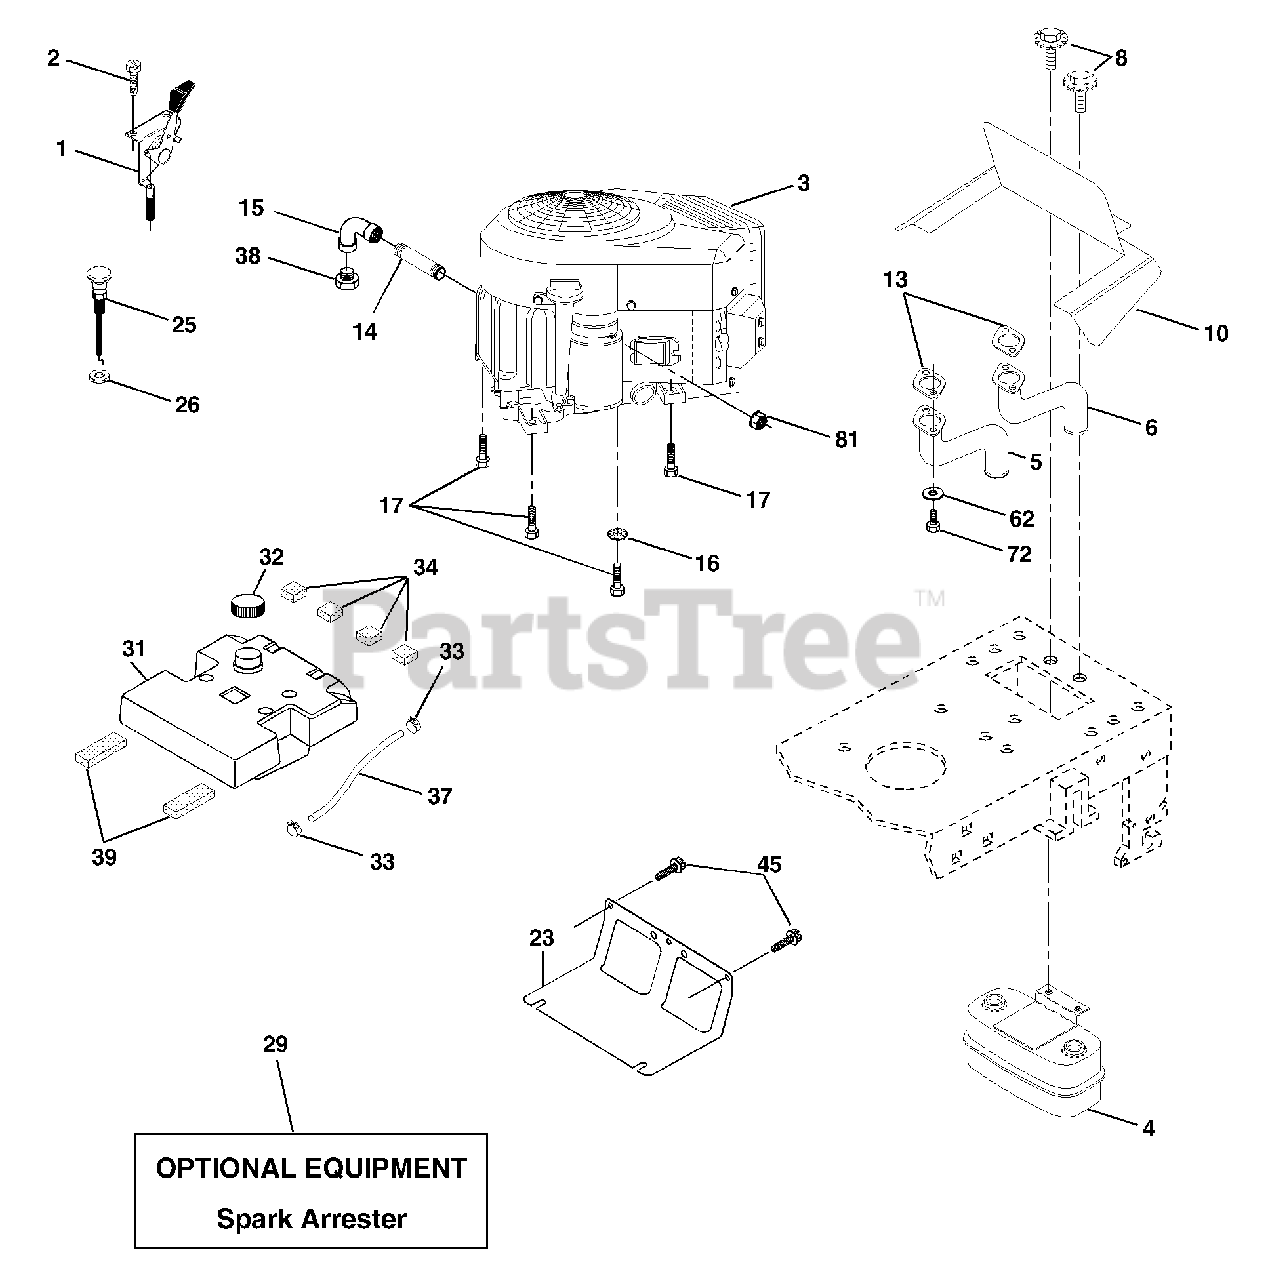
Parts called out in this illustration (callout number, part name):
1	Control Throttle
2	Screw Hwhd Hi-Lo #13-16 x 3/4
4	Muffler Asm Twin Lo-Tone
5	Pipe Exhaust LH Intek
6	Pipe Exhaust RH Intek
8	Bolt 5/16-18 UNC x 3/4 w/Sems
10	Shield Browning Intek II
13	Muffler Gasket
14	Nipple Pipe 3/8 x 4-1/2"
15	Elbow STD 90 Degree 3/8-18 NPT
16	Washer Lock Ext Tooth 3/8
17	Screw Thdrol 3/8-16 x 1-1/2
23	Shield Heat
25	Choke Control
26	Nut, Keps 3/8-24 UNF
29	Kit Spark Arrestor (Flat Scrn)
31	Tank Fuel 3 50 Rear
32	Cap Asm Fuel W/sym Vented
33	Clamp Hose Black
34	Pad, Spacer
37	Line Fuel
38	Order Part From Engine Mfg.
39	Pad Idler
45	Screw Hexwsh Thdr 3/8-16 x 3/4
62	Washer Lock 5/16
72	Screw Hex Hd Cap 5/16-18 x 3/4
81	Nut Keps Hex 1/4-20 UNC
